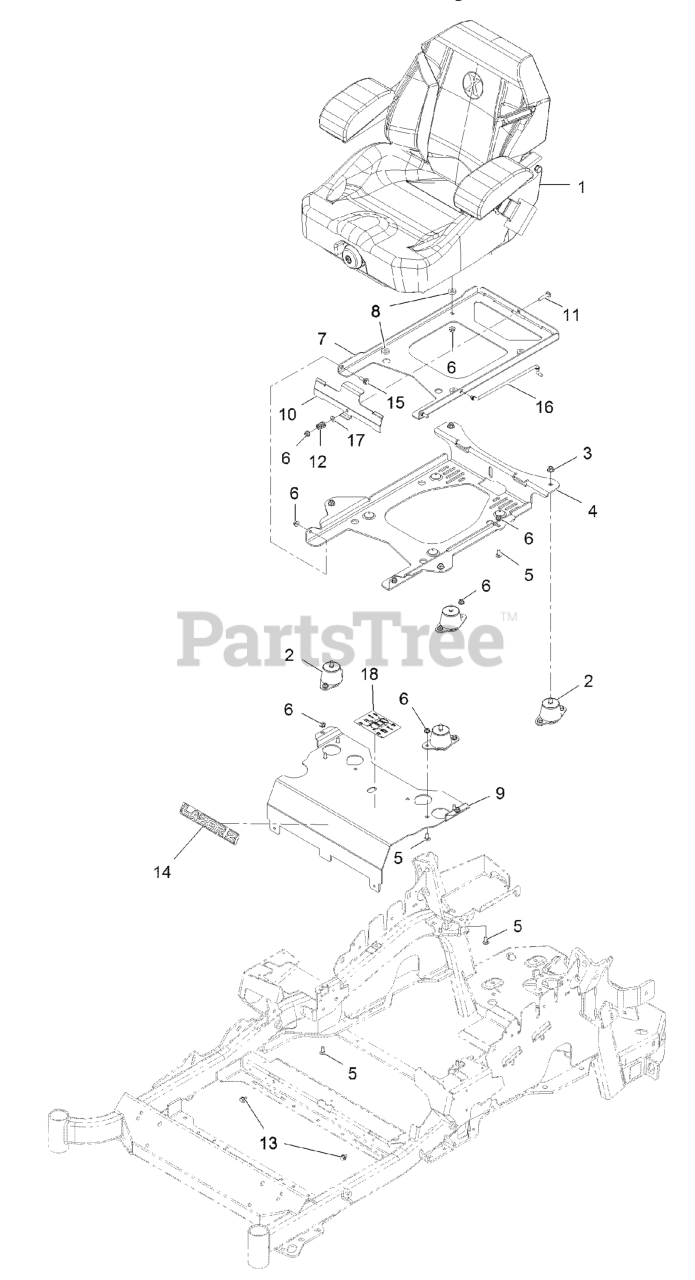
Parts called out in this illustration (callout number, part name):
1	KIT-SUSPENSION SEAT
2	ISOLATOR-SEAT
3	NUT-HF, NI
4	PLATE-TILT, SEAT SUPPORT
5	SCREW-CARR
6	NUT-HF, NI
7	PLATE-FRAME, SEAT
9	Panel-Front, Seat Mount
10	PLATE-LATCH, SEAT
11	BOLT-CARR
12	SPRING-COMPRESSION
14	DECAL, LAZER MODEL
15	SCREW-SHOULDER
16	ROD-PROP
17	WASHER-PLAIN
18	DECAL-SERVICE AID
